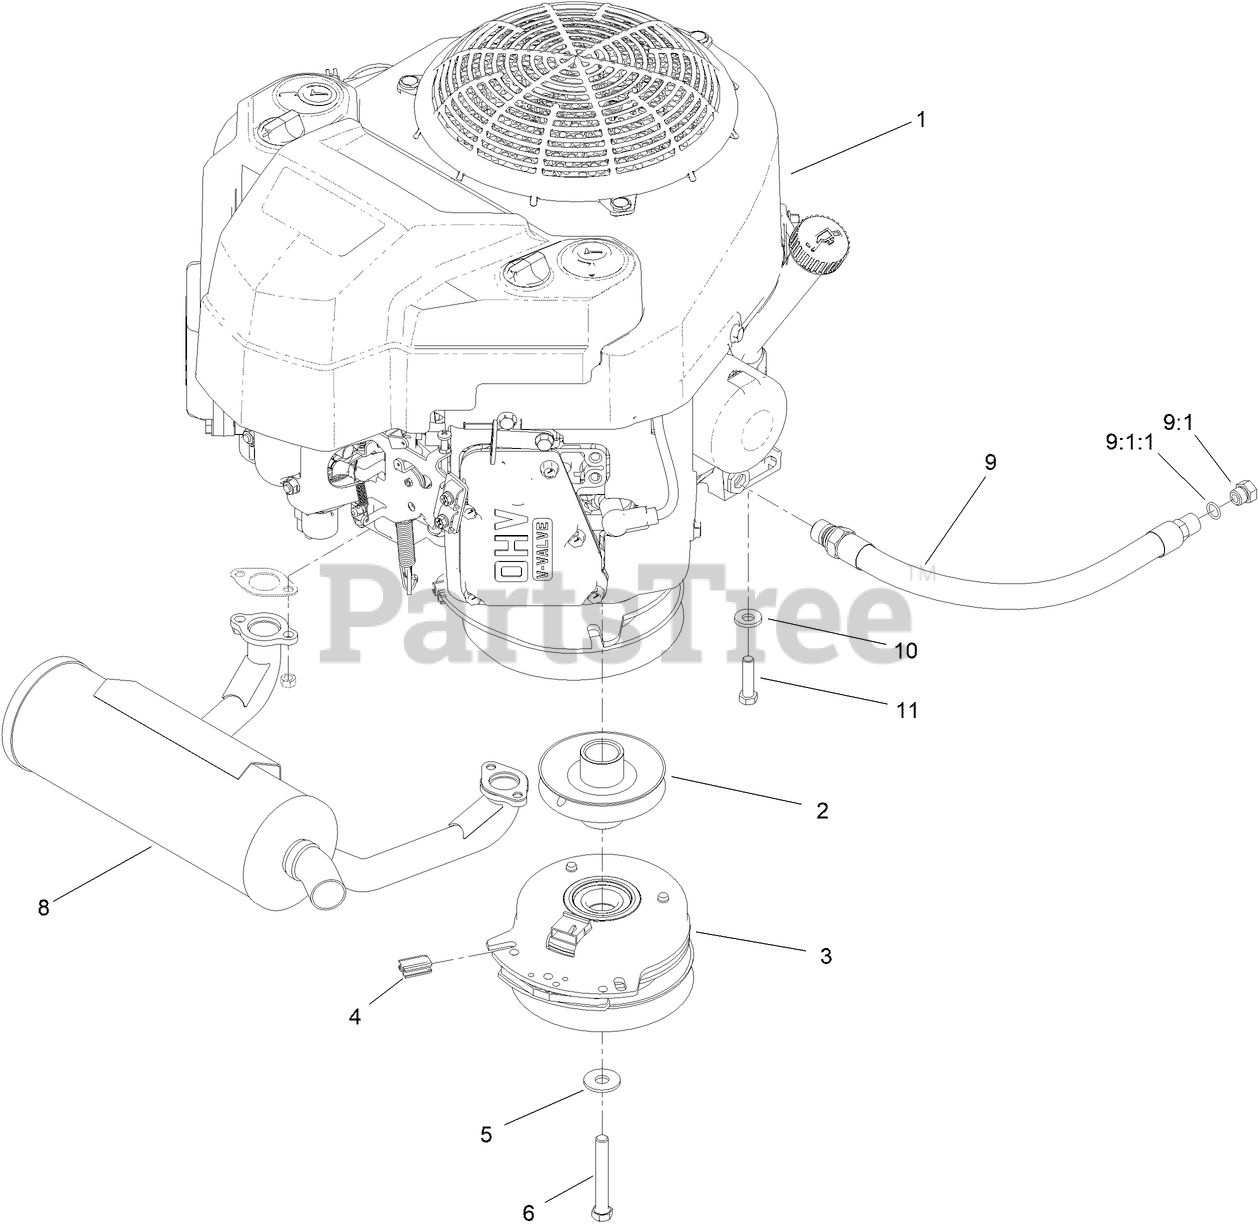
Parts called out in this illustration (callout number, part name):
2	PULLEY
3	CLUTCH-PTO
4	ISOLATOR-CLUTCH
5	WASHER-HARDENED
6	SCREW-HH W/LOCTITE
8	MUFFLER-HORIZONTAL
9	Asm-Oil Drain Hose W/Plug
9:1	PLUG-HH
9:1:1	O-RING
10	WASHER-BELLEVILLE
11	SCREW-HH
